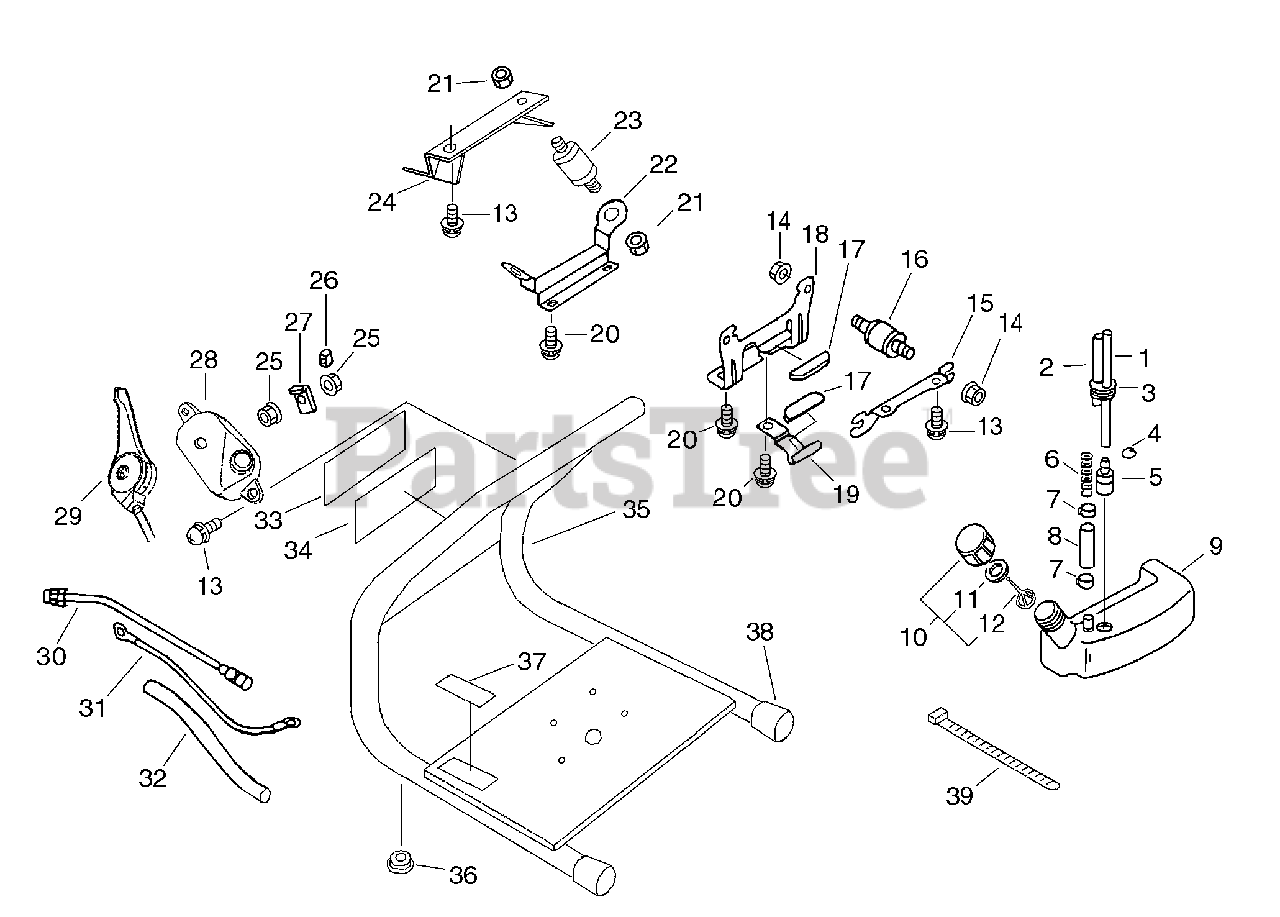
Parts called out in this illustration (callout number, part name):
1	Pipe, Oil
2	Pipe 3x6x100
3	Grommet
5	Strainer, Fuel
6	Spring,Compression
9	Tank, Fuel
10	Cap Assy, Fuel Tank
11	Gasket, Fuel Cap
12	Clip, Fuel Cap
13	Screw 5x12
14	Nut, Flange 5
15	Bracket Engine
17	Cushion,Fuel Tank
18	Bracket,Fuel Tank
19	Bracket Fuel Tank
20	Screw 6x14
22	Plate,Angle
24	Plate,Angle
27	Fixed Plate
28	Bracket, Throttle
29	Throttle,Contorl
30	Stop Switch
33	Label,Echo
34	Label,Model
36	Grommet,Circular
37	Label, Caution
38	Cap,Cushion
